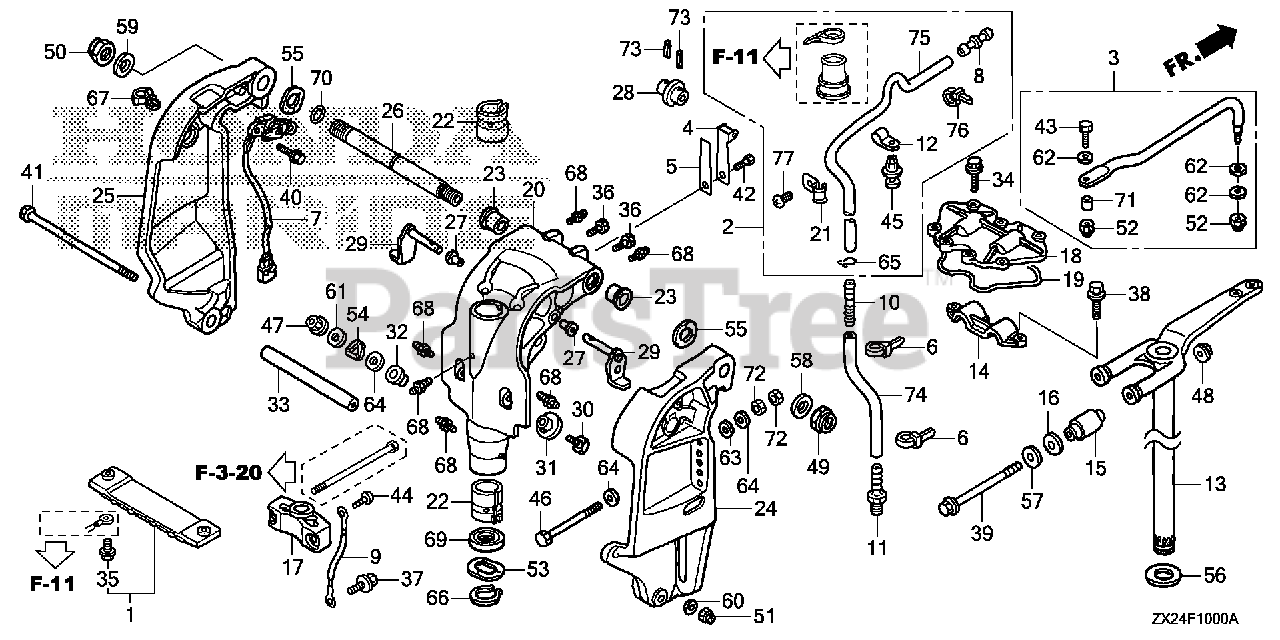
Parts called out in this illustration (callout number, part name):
1	METAL KIT, ANODE
2	TUBE KIT, SPEED SENSOR
3	ROD KIT, STEERING
4	SPRING, CLICK
5	SPRING, CLICK ASSIST
6	BAND, WIRE
7	SENSOR ASSY., TRIM ANGLE
8	JOINT B, WASHER TUBE (MITSUBA)
9	WIRE, LEAD (1.5X116MM)
10	END, NIPPLE
11	NIPPLE, SENSOR
12	CLAMP, SENSOR TUBE
13	FRAME, MOUNTING (XL)
14	HOUSING, MOUNTING (UPPER)
15	MOUNT, RUBBER (UPPER)
16	RUBBER, MOUNT STOPPER (UPPER)
17	HOUSING, CENTER MOUNTING (LOWER) (XL)
18	COVER, MOUNT (UPPER)
19	SEAL, MOUNT COVER (UPPER)
20	CASE, SWIVEL *NHB14M* (AQUA MARINE SILVER METALLIC)
20	CASE, SWIVEL *NH565* (GRAND PRIX WHITE)
21	CLAMP, TUBE
22	LINER, SWIVEL CASE
23	BUSH, SWIVEL CASE
24	BRACKET, R. STERN *NHB14M* (AQUA MARINE SILVER METALLIC)
24	BRACKET, R. STERN *NH565* (GRAND PRIX WHITE)
25	BRACKET, L. STERN *NHB14M* (AQUA MARINE SILVER METALLIC)
25	BRACKET, L. STERN *NH565* (GRAND PRIX WHITE)
26	SHAFT, TILTING
27	BUSH, TILT ARM
28	BRACKET, TILTING
29	STOPPER, TILT
30	RECEIVER, THRUST
31	BUSH A, THRUST RECEIVE
32	BUSH B, THRUST RECEIVE
33	COLLAR, CYLINDER (LOWER)
34	BOLT, FLANGE (6X20)
35	BOLT, FLANGE (6X23)
36	BOLT (1/4-28UNF)
37	BOLT, FLANGE (6X12)
38	BOLT-WASHER (10X32)
39	BOLT, HEX. (12X200)
40	BOLT, FLANGE (6X20)
41	BOLT, HEX. (10X235)
42	BOLT, HEX. (6X14)
43	BOLT (3/8-24UNF)
44	SCREW, PAN (6X8)
45	SCREW, RIVET (5X10)
46	BOLT, HEX. (12X130)
46	BOLT, HEX. (12X119)
47	NUT, SELF-LOCK (6MM)
48	NUT, FLANGE (12MM)
49	NUT, SELF-LOCK (7/8-14UNF)
50	NUT, SELF-LOCK (25X2.0)
51	NUT, FLANGE (10MM)
52	NUT, SELF-LOCK (3/8-24UNF)
53	WASHER, WAVE (40MM)
54	WASHER, WAVE (12MM)
55	WASHER, WAVE (26MM)
56	WASHER, THRUST (34MM)
57	WASHER, MOUNTING STOPPER (UPPER)
58	WASHER (7/8")
59	WASHER (25MM)
60	WASHER, PLAIN (10MM)
61	WASHER, PLAIN (6MM)
62	WASHER (10MM)
63	WASHER, PLAIN (12MM)
64	WASHER, PLAIN (12MM)
65	CLIP, TUBE (B8)
66	CIRCLIP (OUTER) (39MM)
67	CLIP, WIRE HARNESS
68	NIPPLE, GREASE
69	OIL SEAL (39.5X52X6) (ARAI)
70	O-RING (15.54X2.62)
71	COLLAR, STEERING ROD
72	NUT, HEX. (12MM)
73	PIN, SPRING (3X20)
74	BULK HOSE, VACUUM (5X3000) (5X200)
75	BULK HOSE, VACUUM (5X3000) (5X950)
76	BAND, WIRE
77	SCREW, PAN (6X8)
